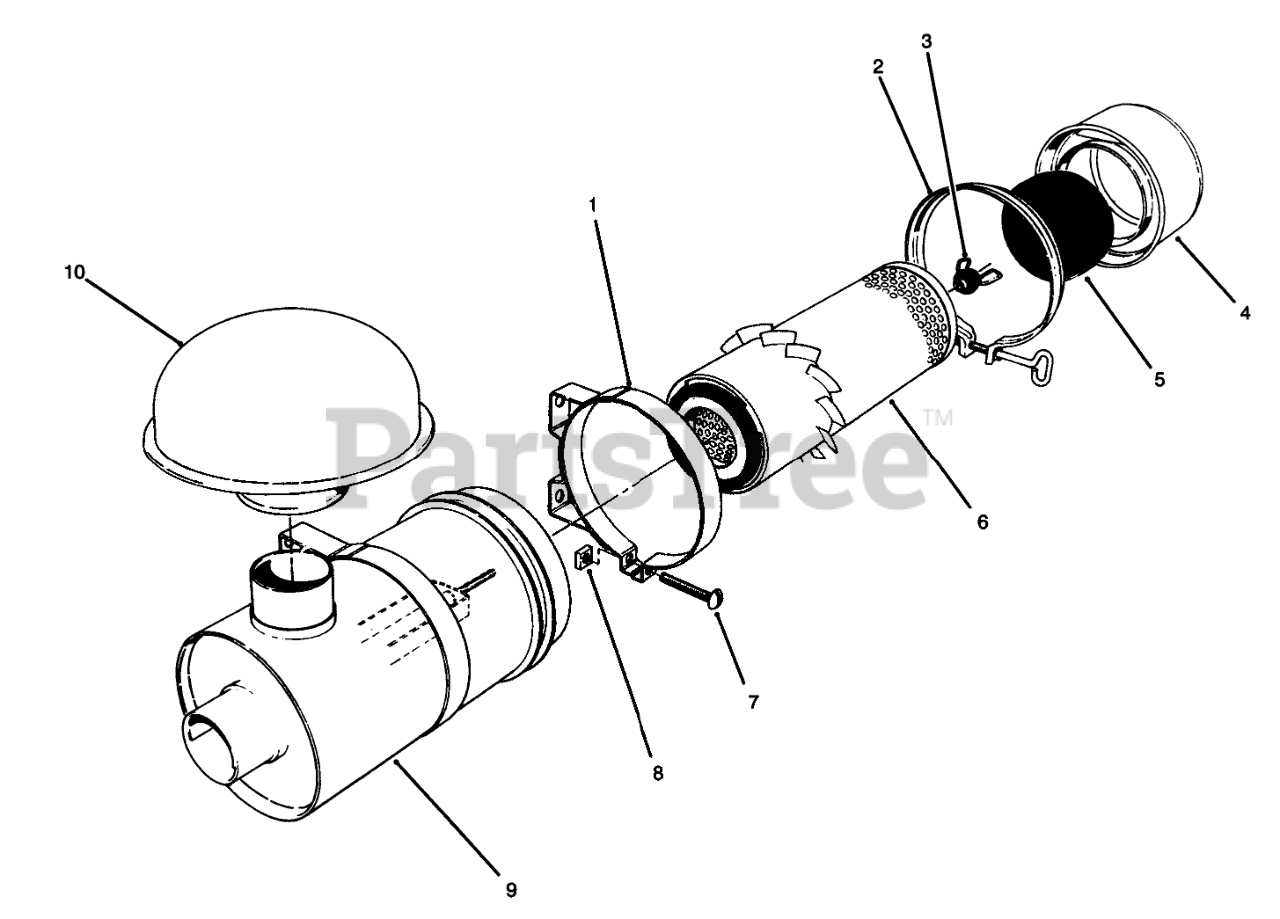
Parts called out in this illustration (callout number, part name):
1	Band Assembly (Incl. Ref. #7 & 8)
2	CLAMP ASM
3	NUT ASM
4	CUP ASM
5	BAFFLE
6	ELEMENT ASM
7	SCREW
8	NUT-SQUARE
9	Body Assembly
10	HOOD-INLET, AIR
